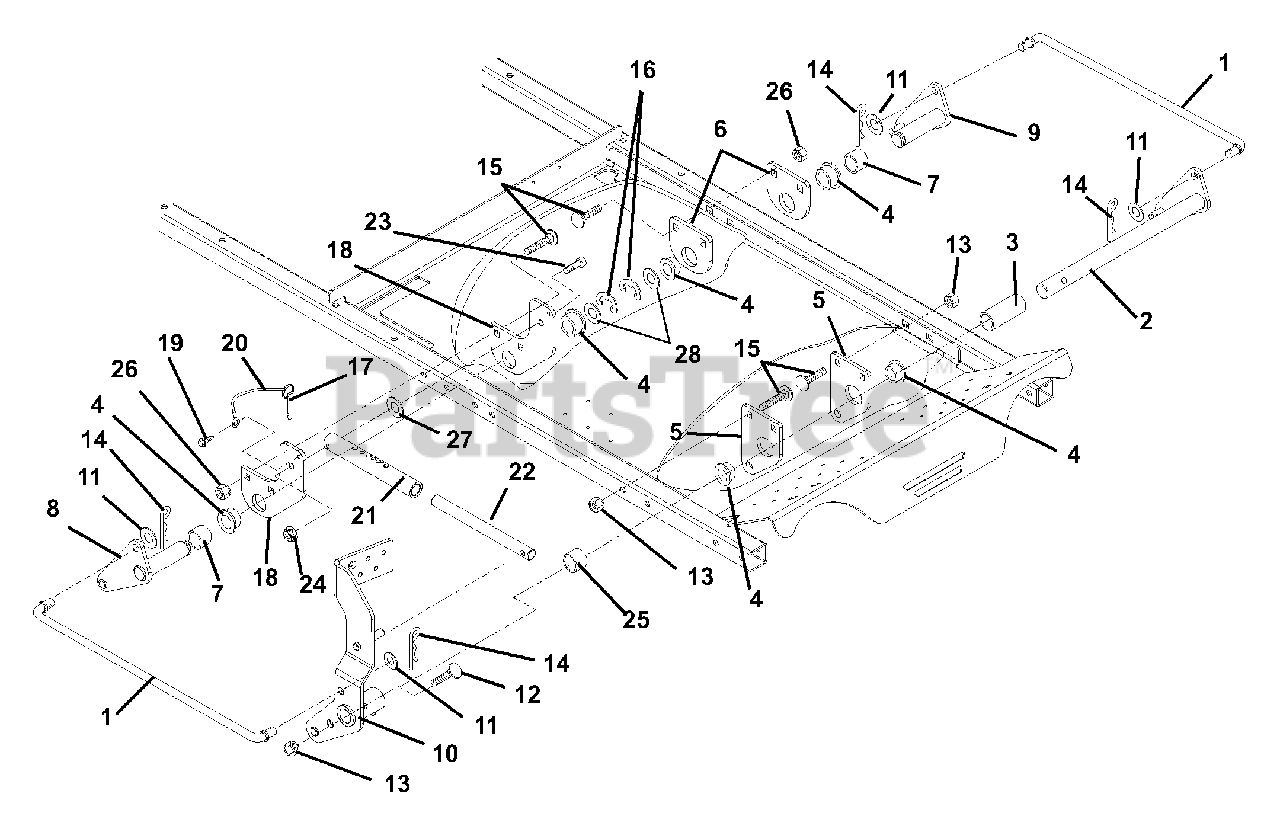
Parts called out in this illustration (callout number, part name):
1	ROD, LIFT
2	WELDMENT,FRONT LIFT
3	BUSHING, FRONT
4	BSHG-FLG 1.000X1.12X.62X1.50BR
5	BRACKET, FRONT PIVOT
6	BRACKET,REAR PIVOT
7	BSHG-SPCR 1.032X1.250X.88 PM
8	WELDMENT, LIFT, REAR - RH
9	WELDMENT, LIFT, REAR - LH
10	WMT, FOOT PEDAL
11	@WSHR-FL-STL.531X1.06X.095YWZC
12	@BLT-HEX .38-16X2.00 GR5 YWZC
13	@NUT-LK-NYL-FLG .38-16 YWZC
14	PIN, HAIR, EXT - #16 YWZC
15	@BLT-RDHDSQNK .38-16X2.50 G5YZ
16	RG-RTNG .822X1.500X.050 TYP E
17	PIN, SPRING BALL .375OD X 1.50
18	MOUNT, REAR LIFT
19	@SCR-TAP .25-20X.37 HWH YWZ TR
20	CBL,HOOD
21	TUBE, LIFT STOP
22	ROD, LIFT
23	BLT, SKH SHLD .31-18X2.25
24	@NUT-LK-NYL-FLG .31-18 YWZC
25	BSHG, SPCR 1.032X1.25X.25 PM
26	@NUT-LK-TOP-FLG .38-16 YWZC
27	WSHR-FL-STL .390X.75X.125 YWZC
28	WSHR-FL-STL 1.12X1.500X.092 YZ
